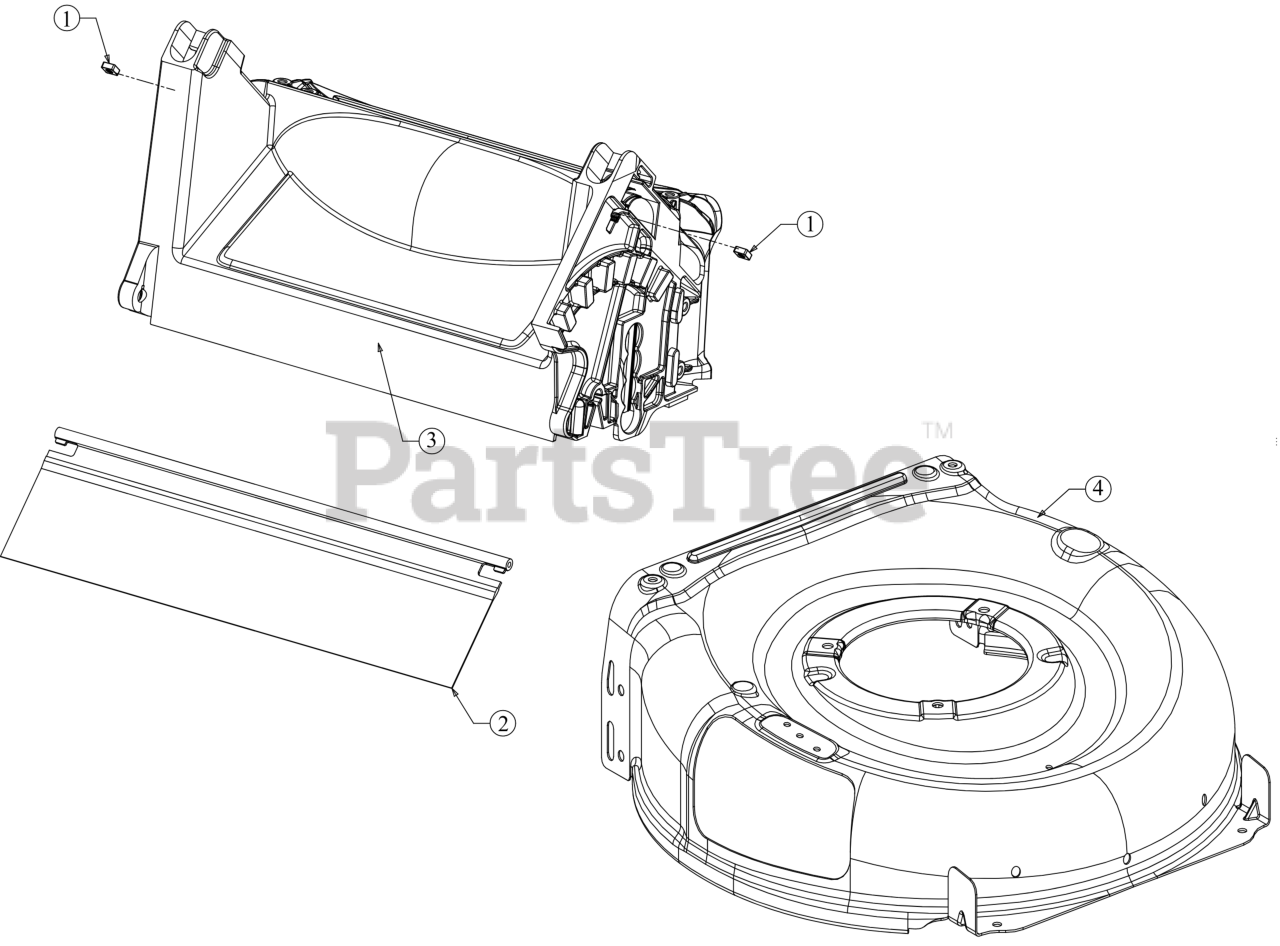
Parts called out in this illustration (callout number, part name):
1	SQUARE NUT 1/4-20
2	TRAILSHIELD
3	REAR BAFFLE ASSEMBLY
4	21" DECK (3N1)
